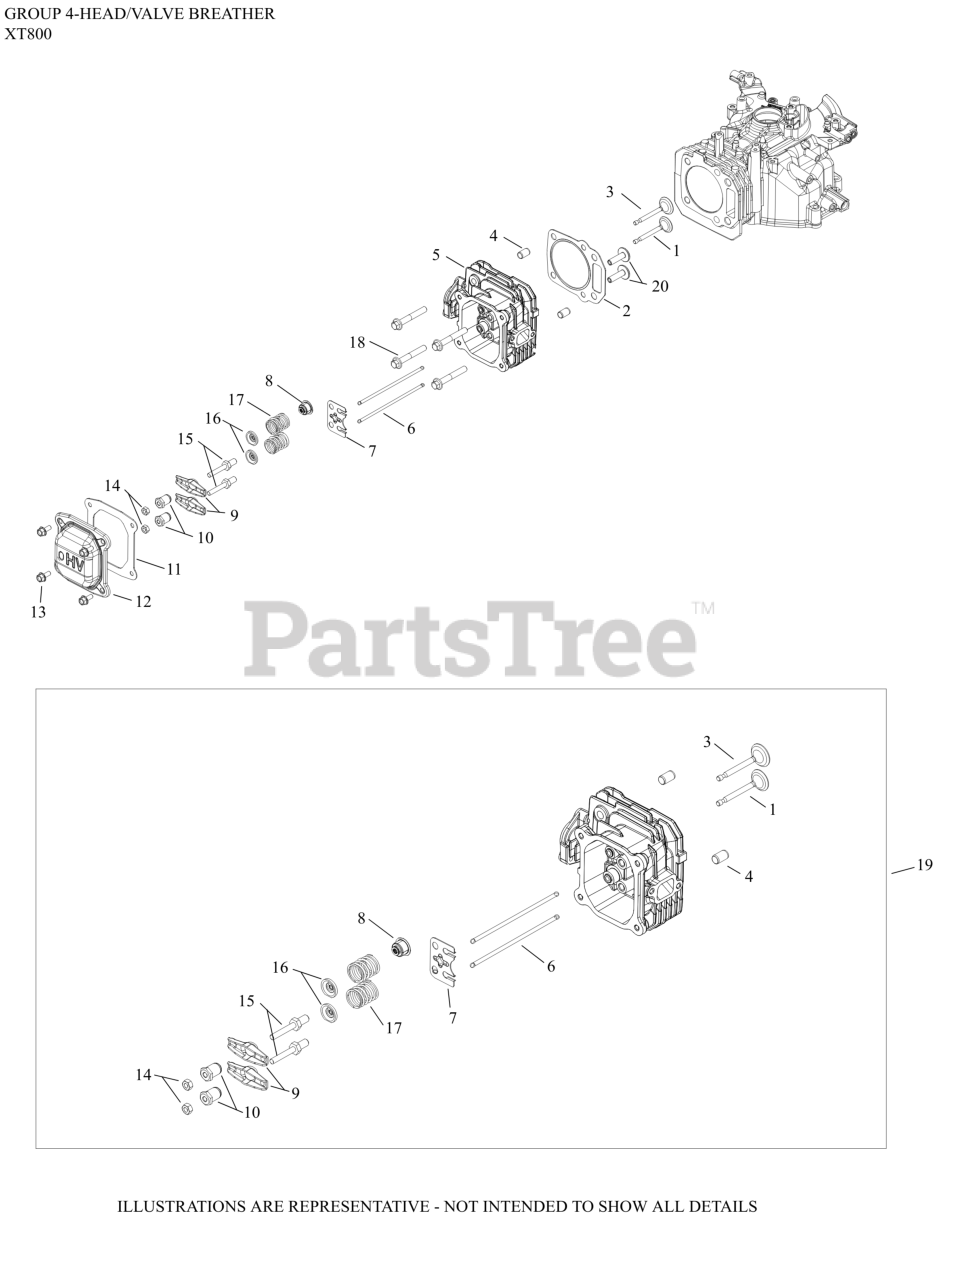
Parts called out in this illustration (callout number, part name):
1	VALVE, EXHAUST
2	KIT, HEAD GASKET-USE 14 841 34-S (XT)
3	VALVE, INTAKE
4	DOWEL, CYLINDER HEAD-(#1438013S)
5	KIT, CYLINDER HEAD-(#DSC)
6	ROD, PUSH
7	PLATE, PUSHROD GUIDE
8	SEAL, VALVE STEM
9	ARM, ROCKER
10	PIVOT, ROCKER ARM
11	GASKET, VALVE COVER
12	COVER, VALVE
14	NUT, HEX JAM
15	STUD, ROCKER ARM
16	RETAINER, VALVE SPRING
17	SPRING, VALVE
18	SCREW, HEX FLANGE M8
19	KIT, VALVE TRAIN
20	LIFTER, VALVE
